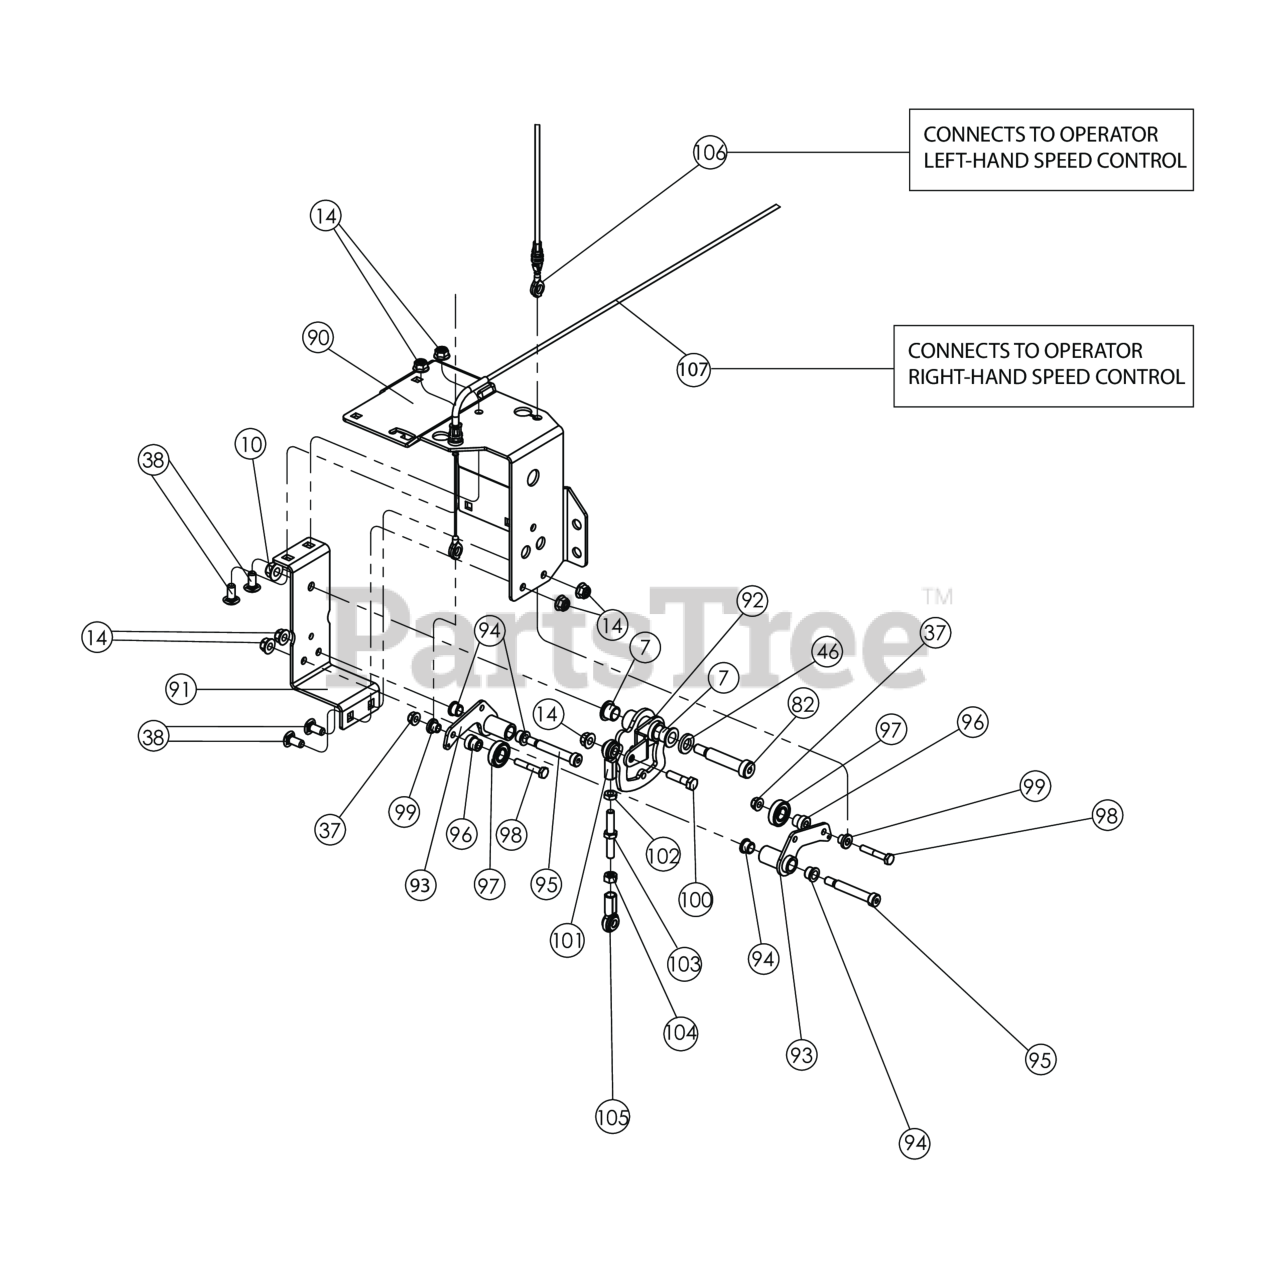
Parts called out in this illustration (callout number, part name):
7	BUSHING .500" ID
10	NUT-HEX-NYLK, FLG .375"-16 ZP
14	NUT-HEX-NYLK, FLG .3125-18 ZP
37	NUT-HEX-NYLK, FLG .250"-20 ZP
38	BOLT CARRIAGE 5/16-18 X 3/4" ZP SHRT NK
46	WSHR-STL,FLT .500"X.875"X.134" MAB ZP
82	BLT-SLDR,SH.500"X2.00",.375"-16X.63"G8ZP
90	ASM, PAINTED CABLE GUIDE W/DECAL
91	PLATE, LONGMEYER BOX MNT
92	WA, EQUAL SPEED CAM
93	BELLCRANK SPEED CONTROL BC26
94	BUSHING 3/8 ID X 1/2 OD X 3/8
95	BOLT SHOULDER 3/8" X 1 3/4"
96	SPACER. SPEED CONTROL STEPPED PM
97	BEARING 1/2" ID X 1.125 OD
98	SCREWCAP 1/4"-20X1 1/2" HCS ZP
99	SPACER, SPEED CONTROL EYELET PM
100	SCREWCAP 5/16"-18X1 1/4" HEX ZP
101	SPHERICAL ROD END MSF-5
102	NUT-HEX, JAM, .3125"-24 G2 YZ
103	JACKSCREW 5/16"-24 RT AND LFT
104	NUT 5/16"-24 LEFT HAND FIN HEX ZP
105	SPHERICAL ROD END FEMALE 5/16"-24 LFT
106	SEE: 351219-S
107	CABLE, SPEED CONTROL ASSY PL
